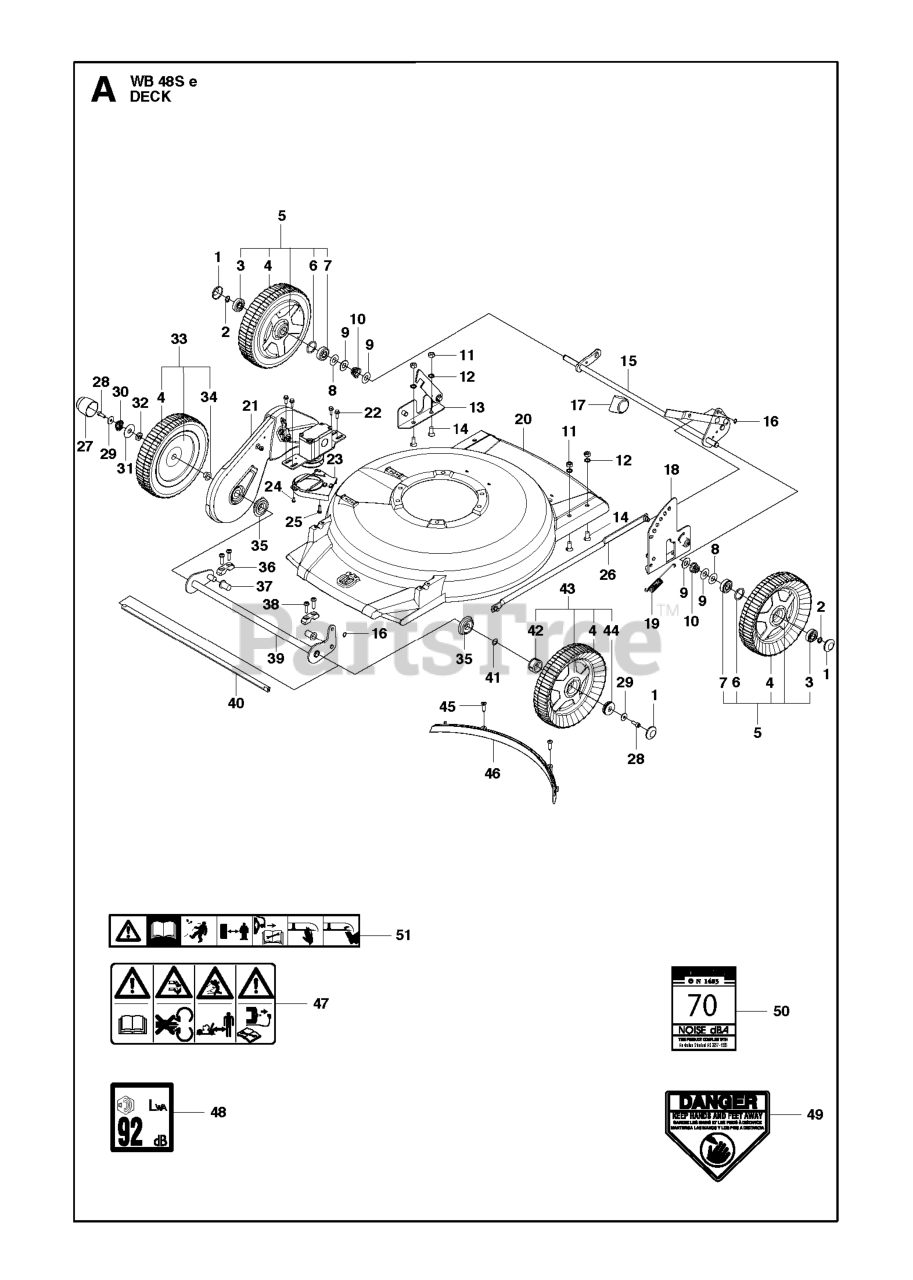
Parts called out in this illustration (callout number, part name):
11	NUT
16	RETAINING RING SGA 8
49	LABEL, DANGER
